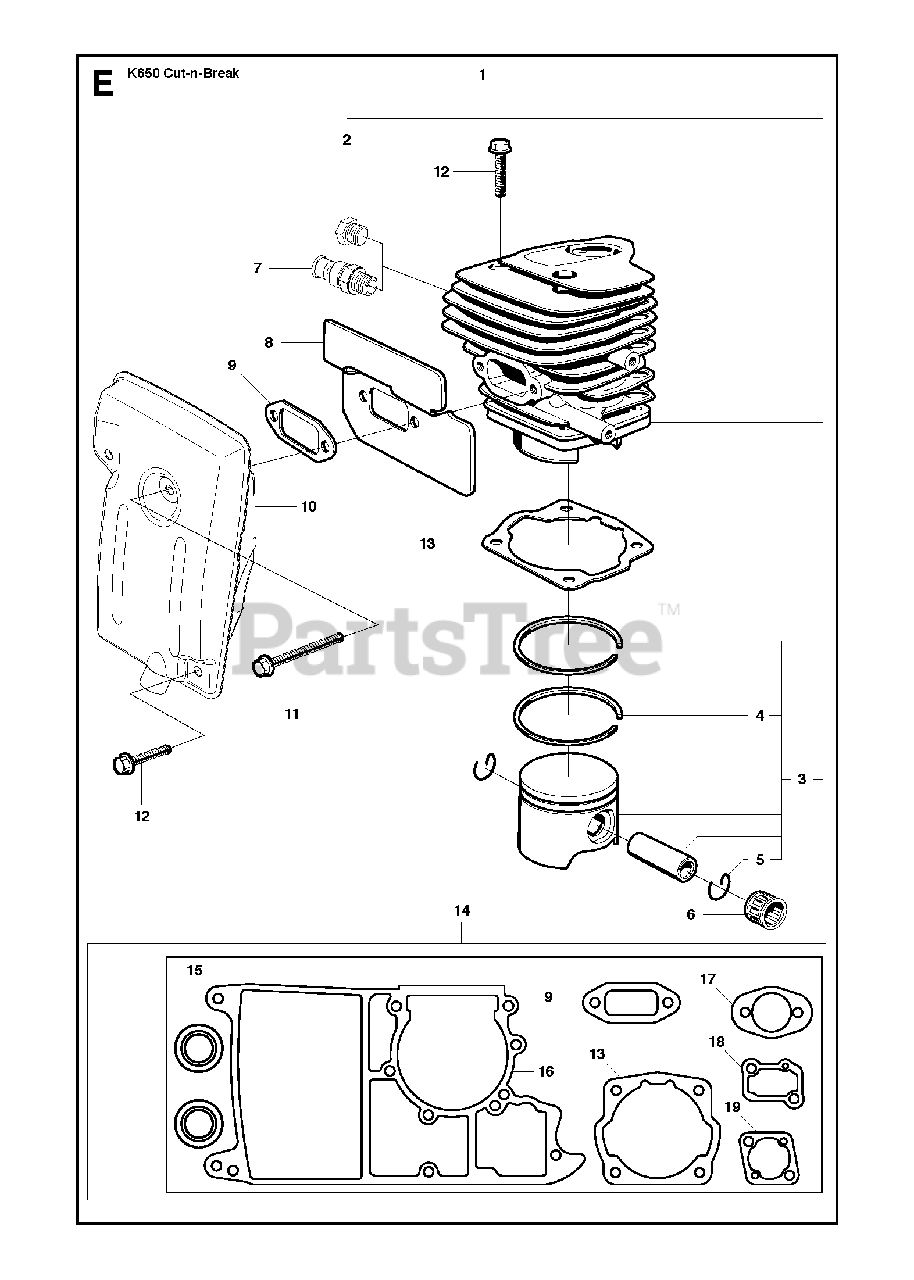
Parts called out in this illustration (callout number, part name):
1	CYLINDER ASSYIncl. 2, 3
3	PISTON ASSYIncl. 4, 5
6	NEEDLE BEARING
7	DECOMPRESSION VALVE
12	SCREW EHHFM
13	GASKETGasket kit 14
14	GASKET KITIncl. 9, 13, 15 - 19
15	SEALING RING
